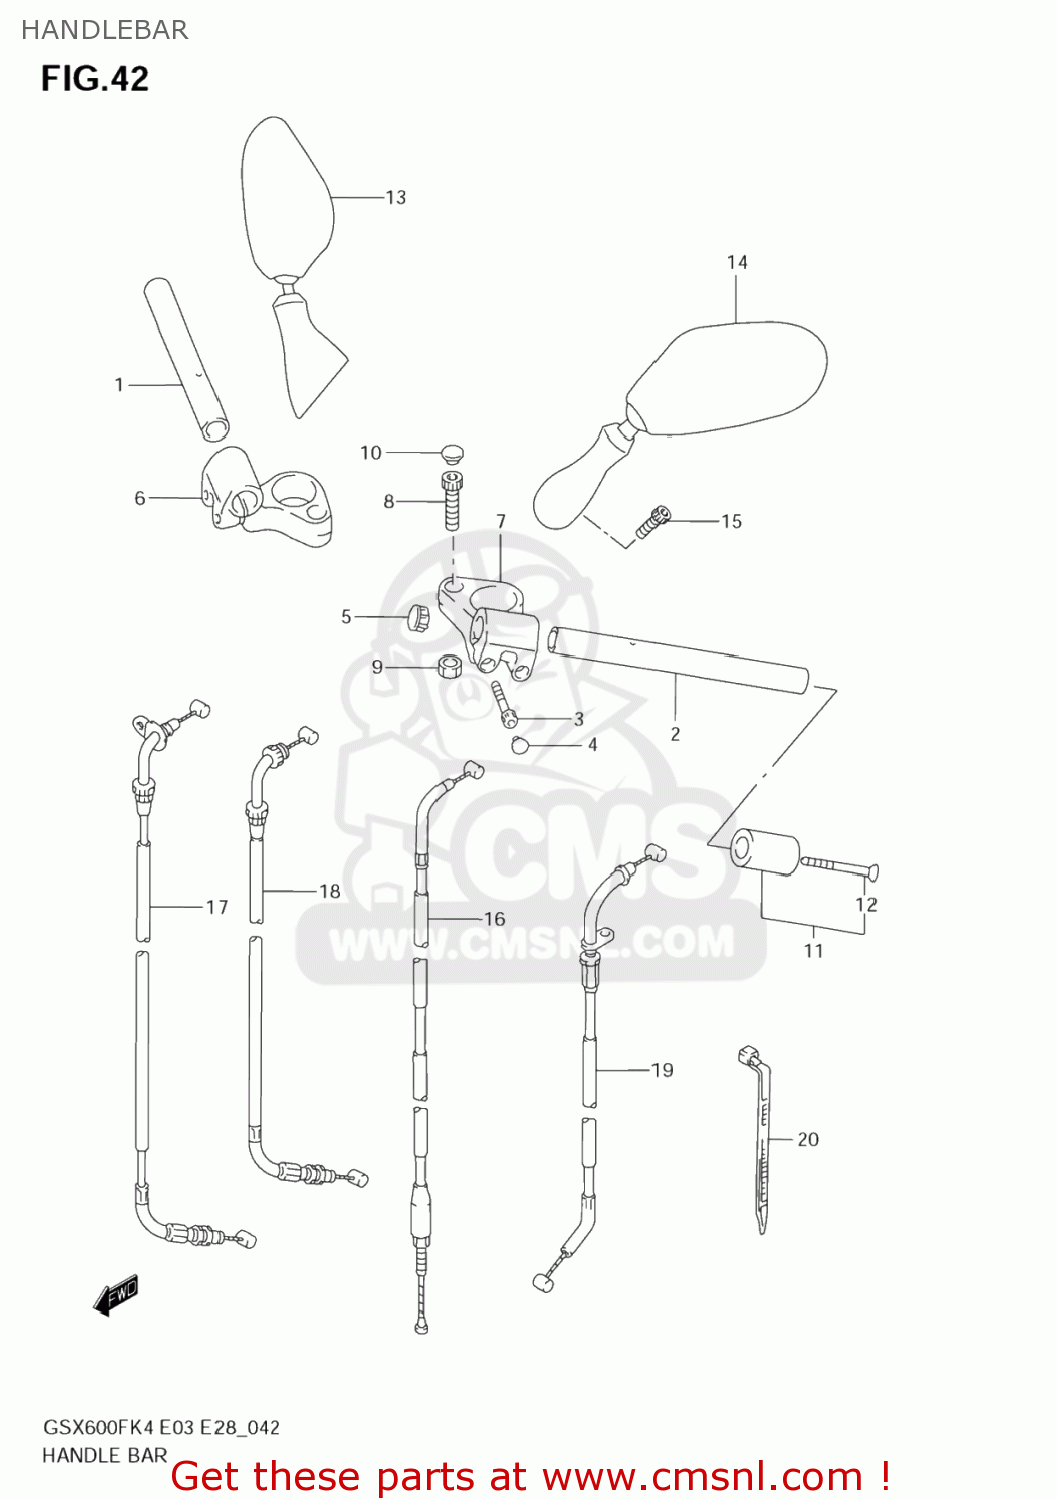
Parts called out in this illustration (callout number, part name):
1	HANDLEBAR,R
2	HANDLEBAR,L
3	BOLT
4	CAP(OD:10)
5	CAP,HANDLEBAR
6	HOLDER,HANDLEBAR,R
7	HOLDER,HANDLEBAR,L
8	BOLT(10X50)
9	NUT
10	CAP(OD:20)
11	BALANCER SET,HANDLEBAR
12	SCREW
13	MIRROR ASSY,RR VIEW,R
14	MIRROR ASSY,RR VIEW,L
15	BOLT,OIL FILLE
16	CABLE ASSY,CLUTCH
17	CABLE ASSY,THROTTLE NO.1
18	CABLE ASSY,THROTTLE NO.2
19	CABLE,STARTER
20	CLAMP(L:95)
